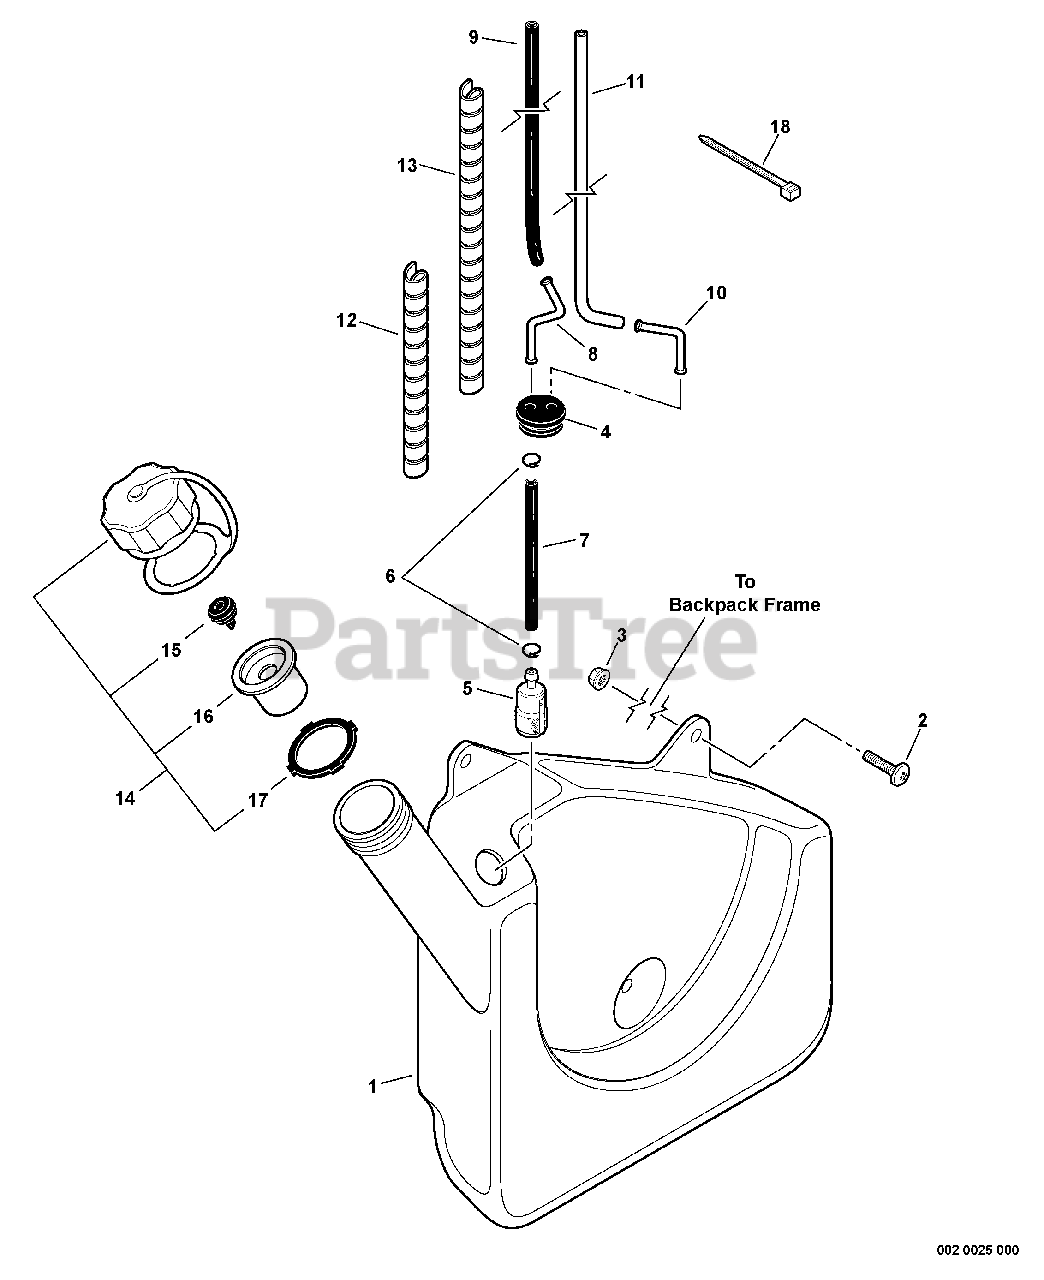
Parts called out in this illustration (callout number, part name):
1	TANK, FUEL
2	SCREW - 5X20
3	NUT - 5 -- FLANGE
4	GROMMET
5	FILTER, FUEL
6	CLIP - 6.5
7	PIPE - 3X6X280 -- BLACK
8	CONNECTOR, PIPE
9	PIPE - 3X7X520 -- BLACK
10	CONNECTOR, PIPE
11	PIPE - 2X4X480 -- CLEAR
12	WRAP, SPIRAL - 130mm
13	WRAP, SPIRAL
14	CAP ASSY
16	VENT HOLDER ASSY
17	GASKET, CAP
18	TIE, CABLE - SMALL
